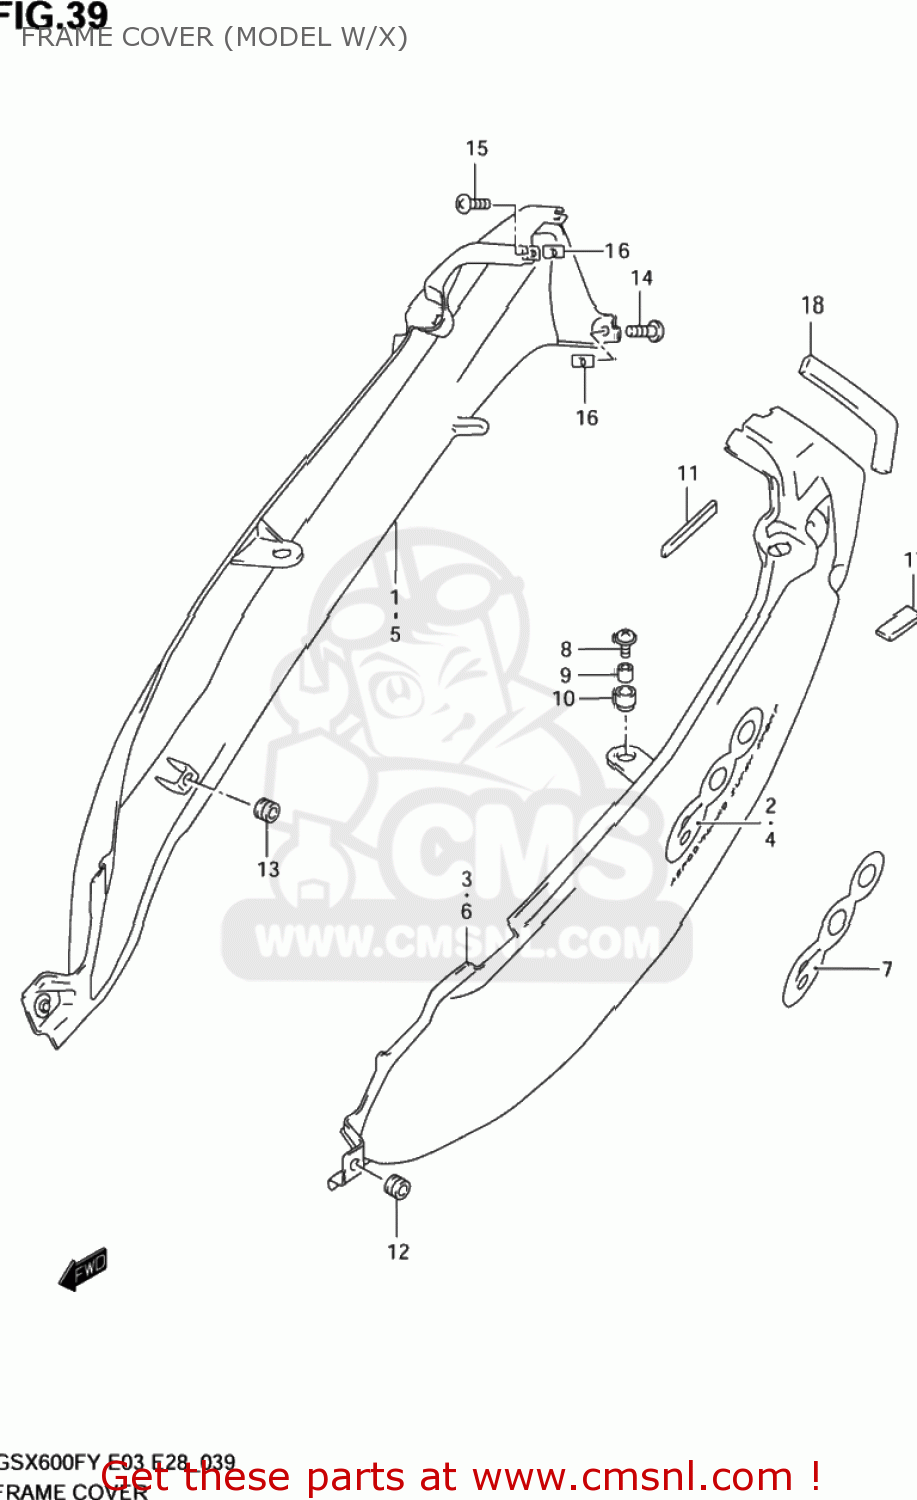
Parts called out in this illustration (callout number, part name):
1	COVER,FRAME,R(BLUE)
2	EMBLEM,FRAME COVER,R
3	COVER,FRAME,L(RED)
4	EMBLEM,FRAME COVER,L
5	COVER,FRAME,R(RED)
6	COVER,FRAME,L(RED)
7	EMBLEM,FRAME COVER
8	SCREW(6X20)
9	SPACER(6.5X10X9.4)
10	CUSHION
11	CUSHION,UNDER COWLING NO.1
12	CUSHION
13	CUSHION
14	SCREW
15	SCREW
16	NUT
17	CUSHION
18	CUSHION,FRAME COVER
